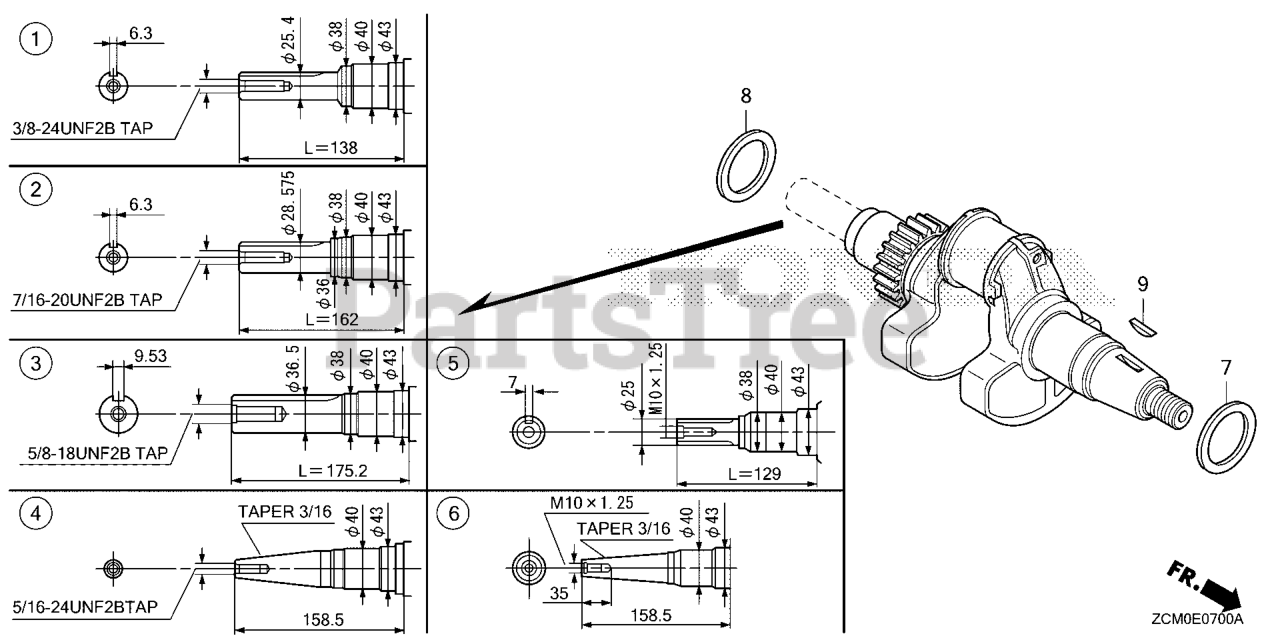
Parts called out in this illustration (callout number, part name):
2	CRANKSHAFT (L=162)
8	WASHER, CRANKSHAFT THRUST
9	KEY, SPECIAL WOODRUFF (25X18)
